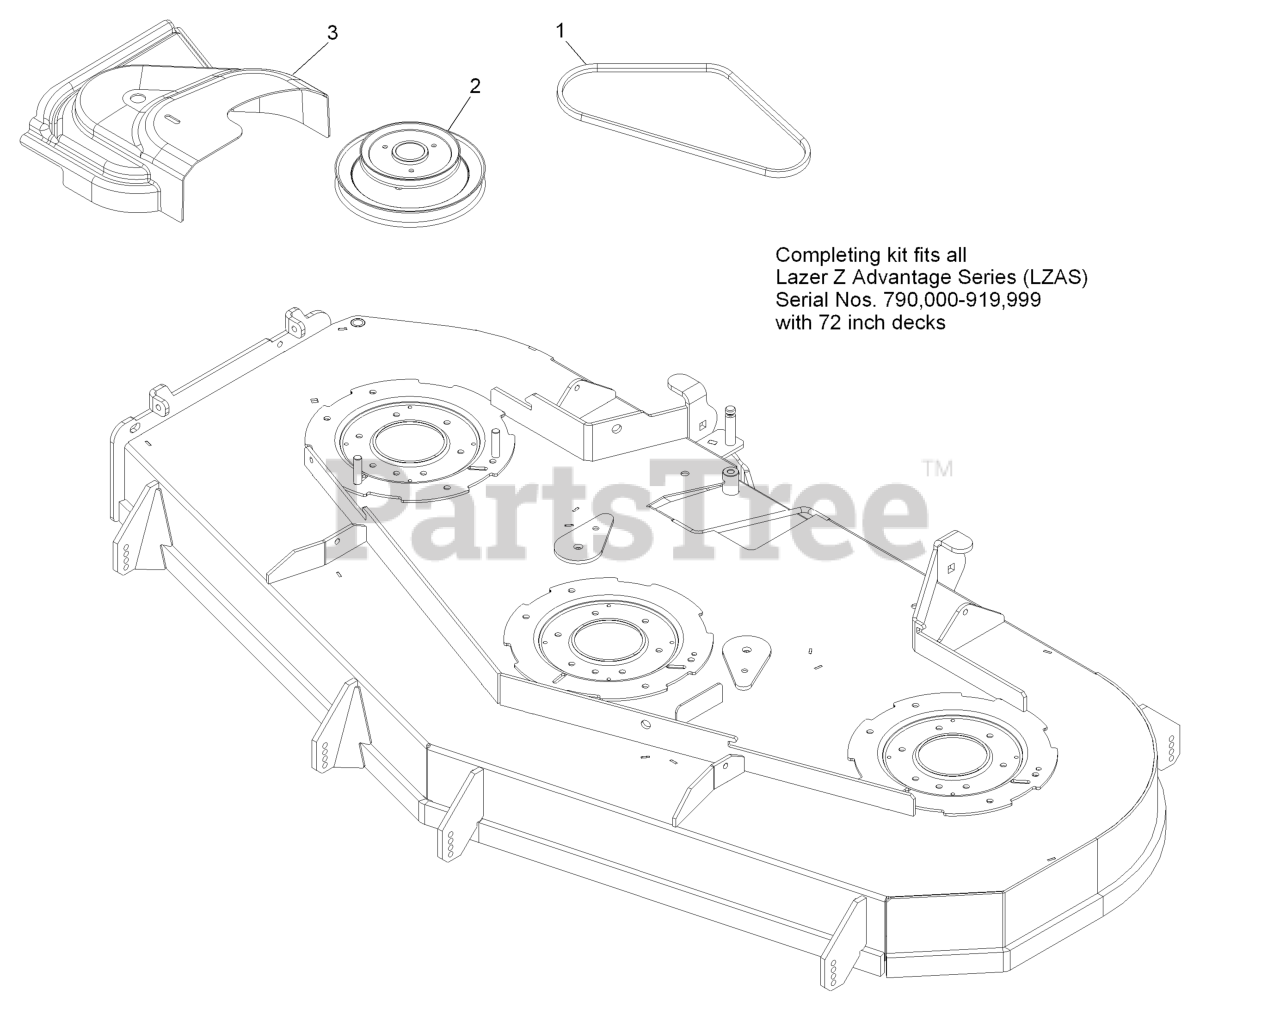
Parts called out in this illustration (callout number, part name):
1	Belt, Blower Drive 72
2	Jackshaft,Uv Drive 724
3	Cover,Belt Uv 72
